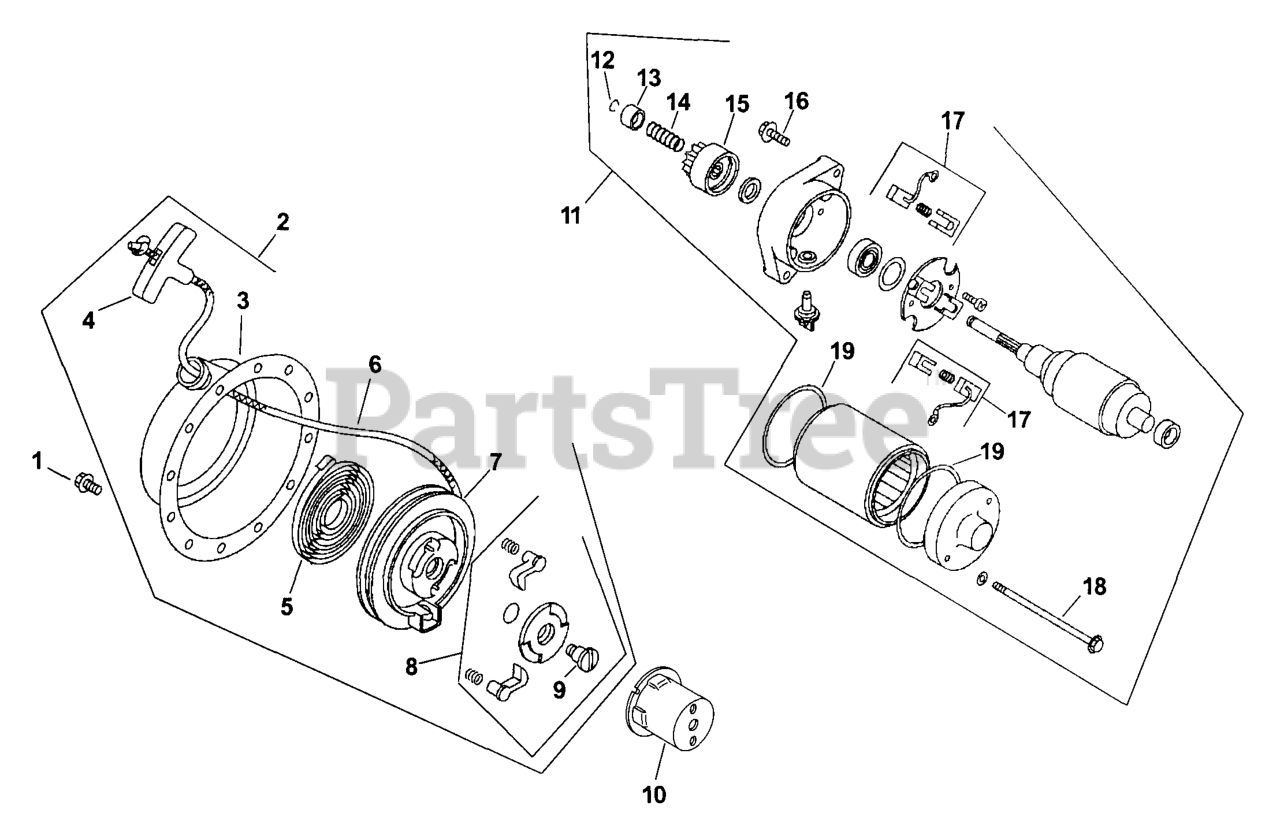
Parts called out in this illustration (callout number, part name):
2	RETRACTABLE STARTER
3	RECOIL HOUSING
5	RECOIL SPRING
8	KIT, PAWL REPAIR (CS4,6)
10	CUP, STARTER DRIVE
